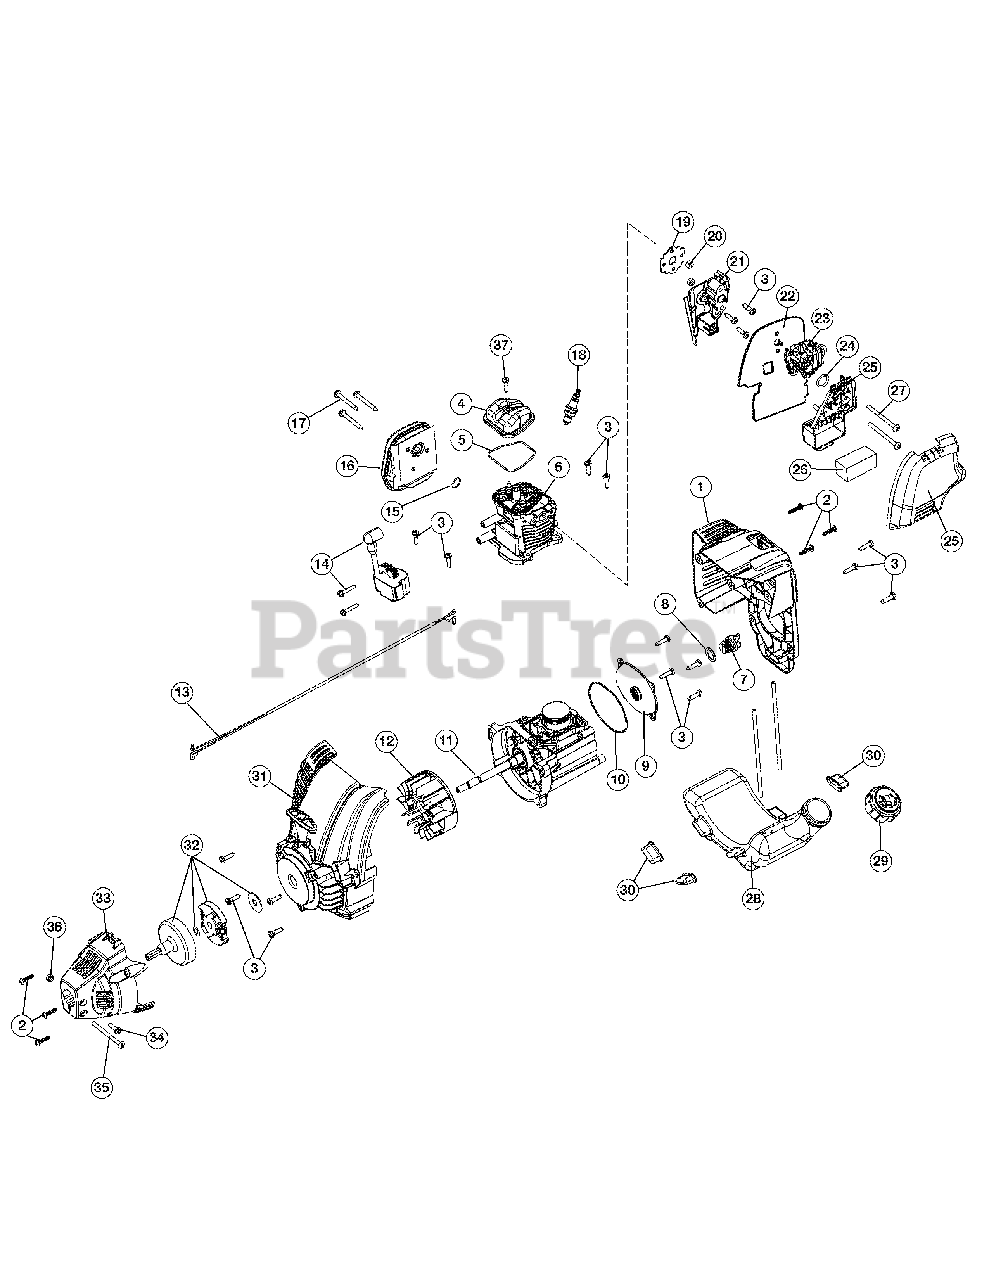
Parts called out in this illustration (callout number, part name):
1	Engine Cover Assembly (Incl. Ref No. 2 & 3)
2	Cover Screw
3	Screw
4	Rocker Cover
5	Rocker Cover O-Ring
6	Cylinder Assembly (Incl. Ref No. 3 & 5)
7	Oil Plug (Incl. Ref No. 8)
8	Oil Plug O-Ring
9	Crankcase Cover
10	Crankcase Cover O-ring
11	Crankcase Assembly (Incl. Ref No. 10)
12	Flywheel Assembly
13	Lead Wires
14	Module Assembly
15	Muffler Gasket
16	Muffler Assembly (Incl. Ref No. 15 & 17)
17	Muffler Screw
18	Spark Plug
19	Insulator Gasket
22	Carburetor Gasket
23	Carburetor
25	Air Cleaner Cover Assembly (Incl. Ref No. 26)
26	Air Filter
28	Fuel Tank Assembly w/Fuel Lines (Incl. Ref No. 29)
30	Fuel Tank Pads
31	Starter Housing Assembly (Incl. Ref No. 3)
32	Clutch Assembly
33	Clutch Cover (Incl. Ref No. 2)
34	Anti-Rotation Screw
35	Clamp Screw
36	Nut
37	Rocker Cover Screw
